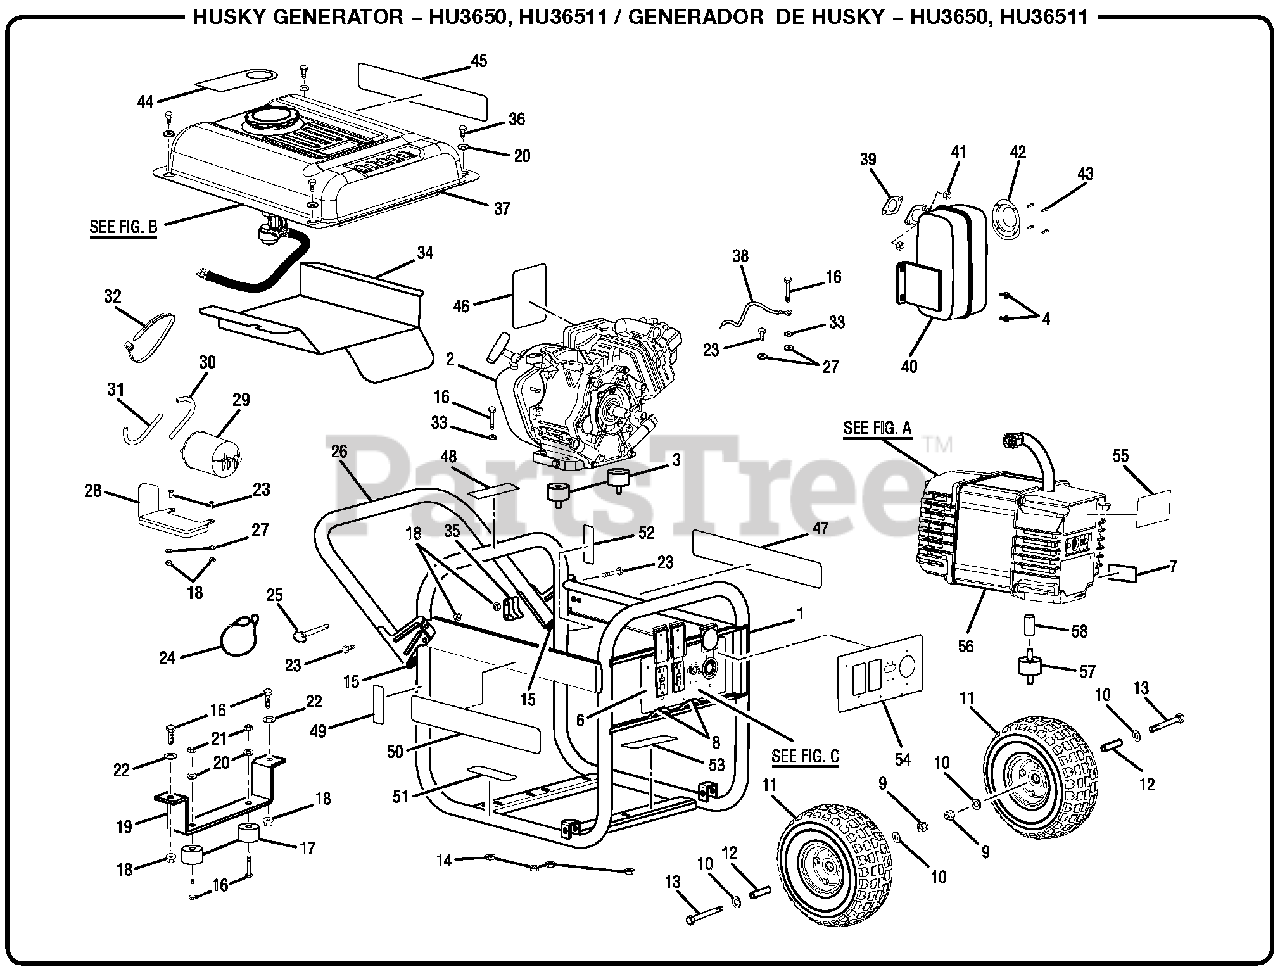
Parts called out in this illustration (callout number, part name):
1	Carrier Assembly
2	Engine (Subaru OHC)
4	Bolt (5/16-24 x 5/8 in.)
5	Bolt (5/16-18 x 2-1/4 in., Hex Hd.)
6	Control Panel (HU3650, See Fig. C)
7	Ground Label
8	Cord Retainer
9	Lock Nut (3/8-16)
10	Washer (3/8 in.)
12	Spacer (3/8 in. ID)
13	Bolt (3/8-16 x 4-1/4 in.)
14	Lock Nut (5/16-18)
16	Bolt (5/16-18 x 1-1/2 in.)
17	Rubber Foot
18	Flange Nut (5/16-18)
19	Foot Bracket
20	Washer (1/4 in.)
21	Lock Nut (1/4-20)
22	Washer (5/16 in.)
23	Bolt (5/16-18 x 3/4 in., Hex Hd.)
25	Release Pin
27	External Star Washer (5/16 in.)
28	Bracket (HU36511, Carb Canister)
29	Canister (HU36511)
30	Purge Hose (HU36511)
31	Rollover Hose (HU36511)
32	Cable Tie (18.6 in.) (HU36511)
33	Lock Washer (5/16 in.)
34	Heat Shield
35	Handle Bracket Spacer
36	Bolt (1/4-20 x 1 in.)
37	Fuel Tank Assembly (HU3650, See Fig. B)
38	Ground Wire Assembly
41	Hex Nut (8 mm)
42	Spark Screen
43	Screw (#8 x 3/8 in.)
44	Danger Hang Tag
45	Quick Start Label
46	Start Label
47	Danger Label
48	Fire Danger Label
49	Lock Pin Label
50	Logo Label
51	Engine Lubricant Label
52	Hot Surface Label
53	Ground Warning Label
54	Control Panel Label (HU3650)
55	Data Label (HU3650)
56	Generator Head Assembly (See Fig. A)
58	Spacer (3/8 in. ID)
